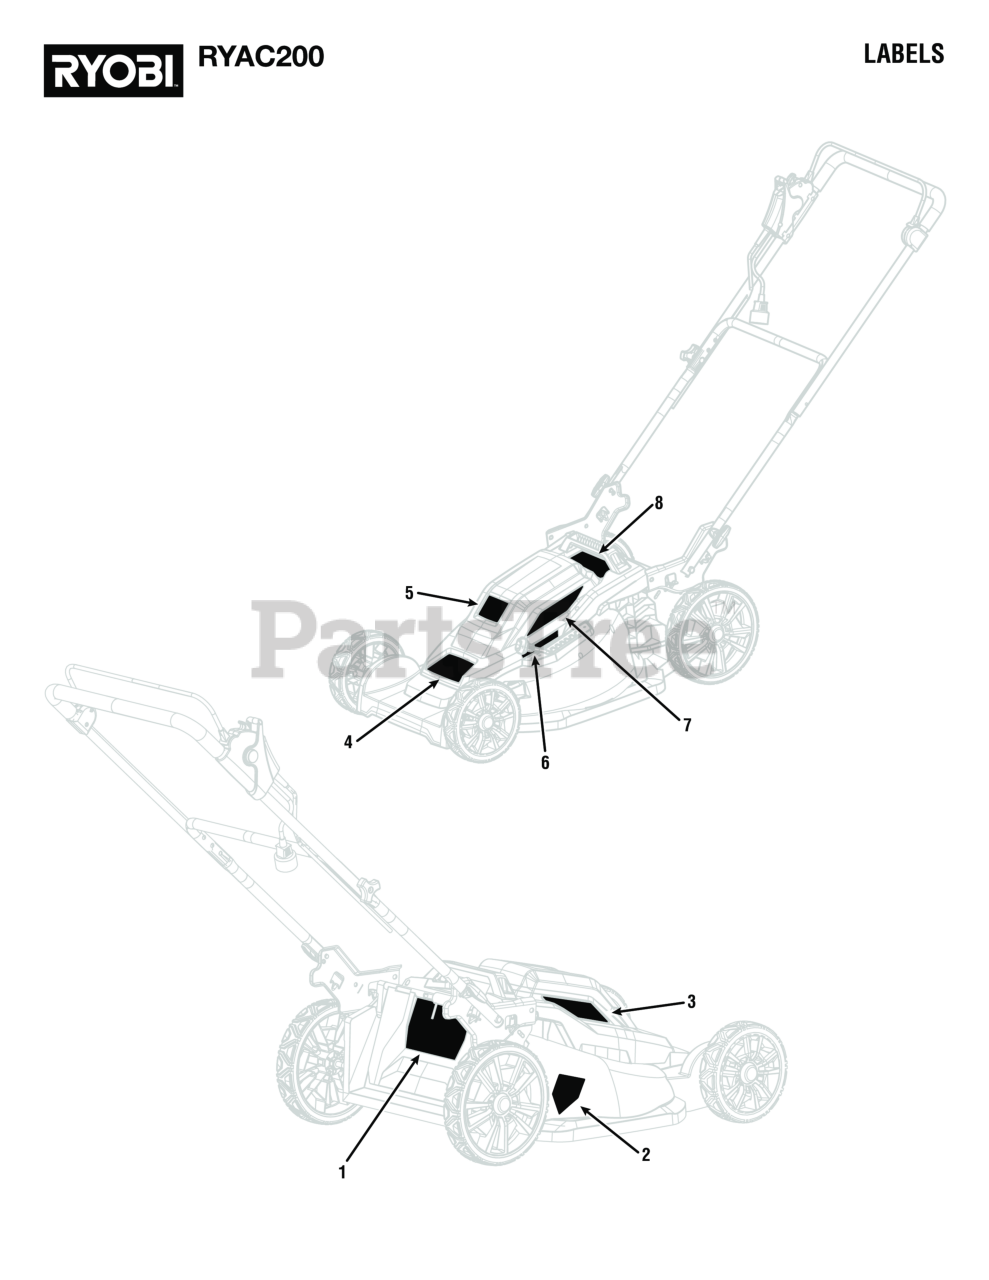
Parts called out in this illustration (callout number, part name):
1	Icons/Danger Label
2	Danger Label (No Hands/Feet)
3	Right Side Logo Label
4	Front Logo Label
5	20 in./13 Amp Callout Front Label
6	Cut Height Label
7	Left Side Logo Label
8	Warnings Overflow/Data Label
